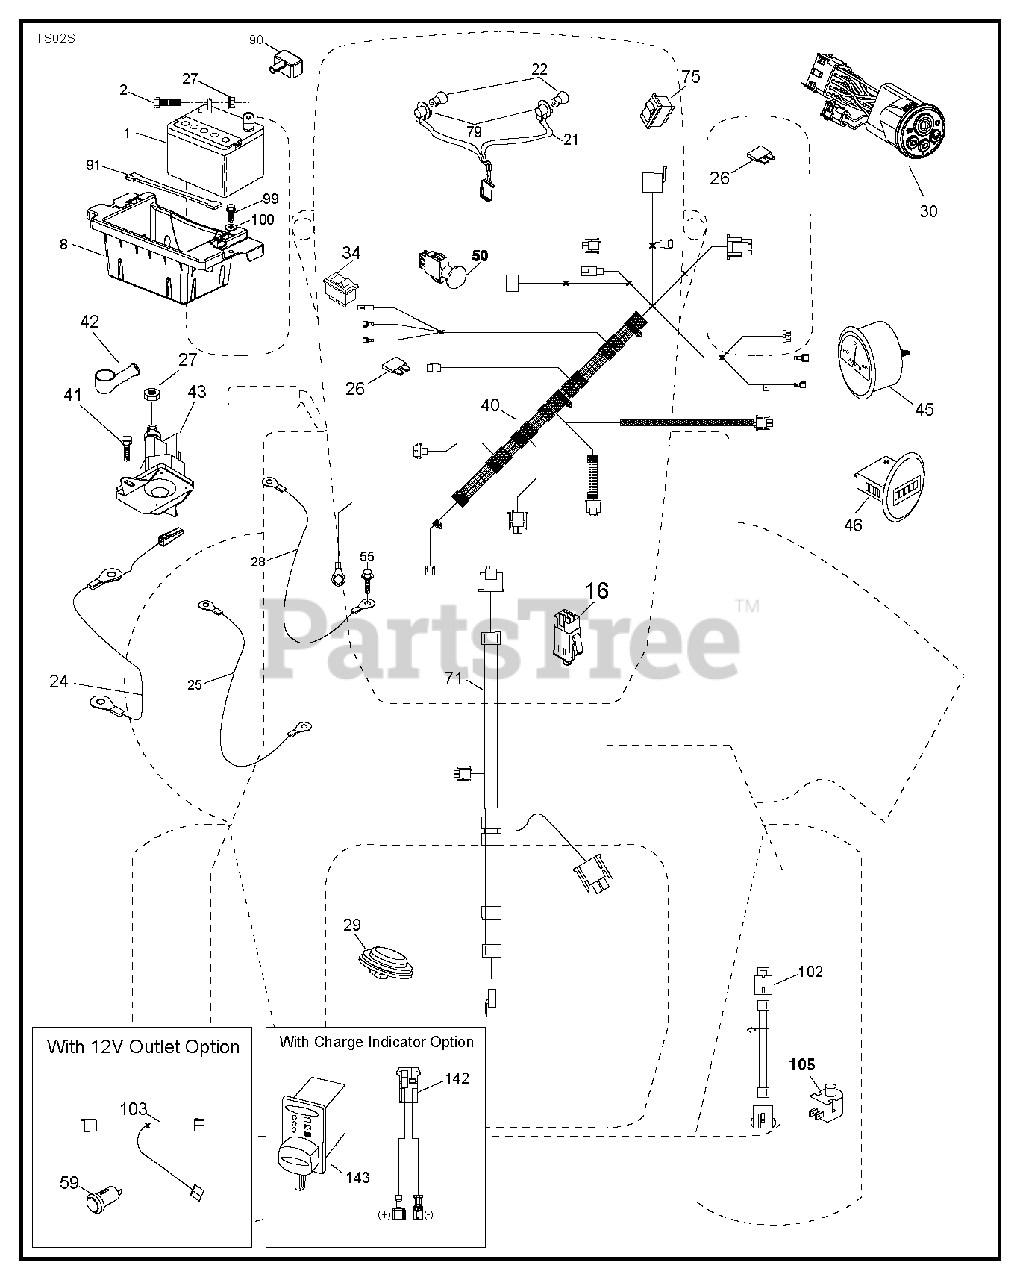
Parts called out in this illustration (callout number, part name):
1	Battery, Dry 30 Amp
2	BOLT.HEX.1/4.X.3/4.DICHROMATE
8	BOX.BATTERY.MOUNT.FRONT.LT
16	SWITCH INTERLOOK PUSH-IN
21	HARNESS.LIGHT W/4152J BULBS
25	CABLE.STARTER.6G.BL/RED.17.5
26	FUSE 20AMP
27	NUT
28	CABLE GROUND 6 GA 21" 90T BLK
29	SWITCH.SEAT.OPC.DELTA.W/3LB.HL
30	2013 TRACTOR SMART SWITCH
34	PLUG.SWITCH.LIGHT.428
40	HARNESS.DASH,SMART.IGN.EDIFF
41	SCREW
42	TERMINAL COVER
43	SOLENOID.W/BRASS.PLUNGER
45	AMMETER GAUGE ROUND SNAP-IN
46	HOURMETER.GAUGE.RNK.SNAPIN.LS
50	RB PTO.SWITCH.8 TERMINAL.BLACK
55	SCREW 5/16"
59	OUTLET.12-VOLT
71	HARNESS CHAS.SMART.IGN
75	SWITCH.ON/OFF.(DIFF.LOCK)
79	BULB HOLDER ASM.
90	COVER.TERMINAL.BATTERY
91	STRAP.BATTERY.MOUNT.FRONT(2 2)
99	SCREW HEXWSHR 1/4-20X3/4
100	WASHER
102	HARNESS PIGTAIL PCH TEX ROS
103	HARNESS.PIGTAIL.12V.OUTLET.
105	REVERSE SWITCH
142	CHARGE.PORT.PIGTAIL HARNESS
143	CHARGE.PORT
